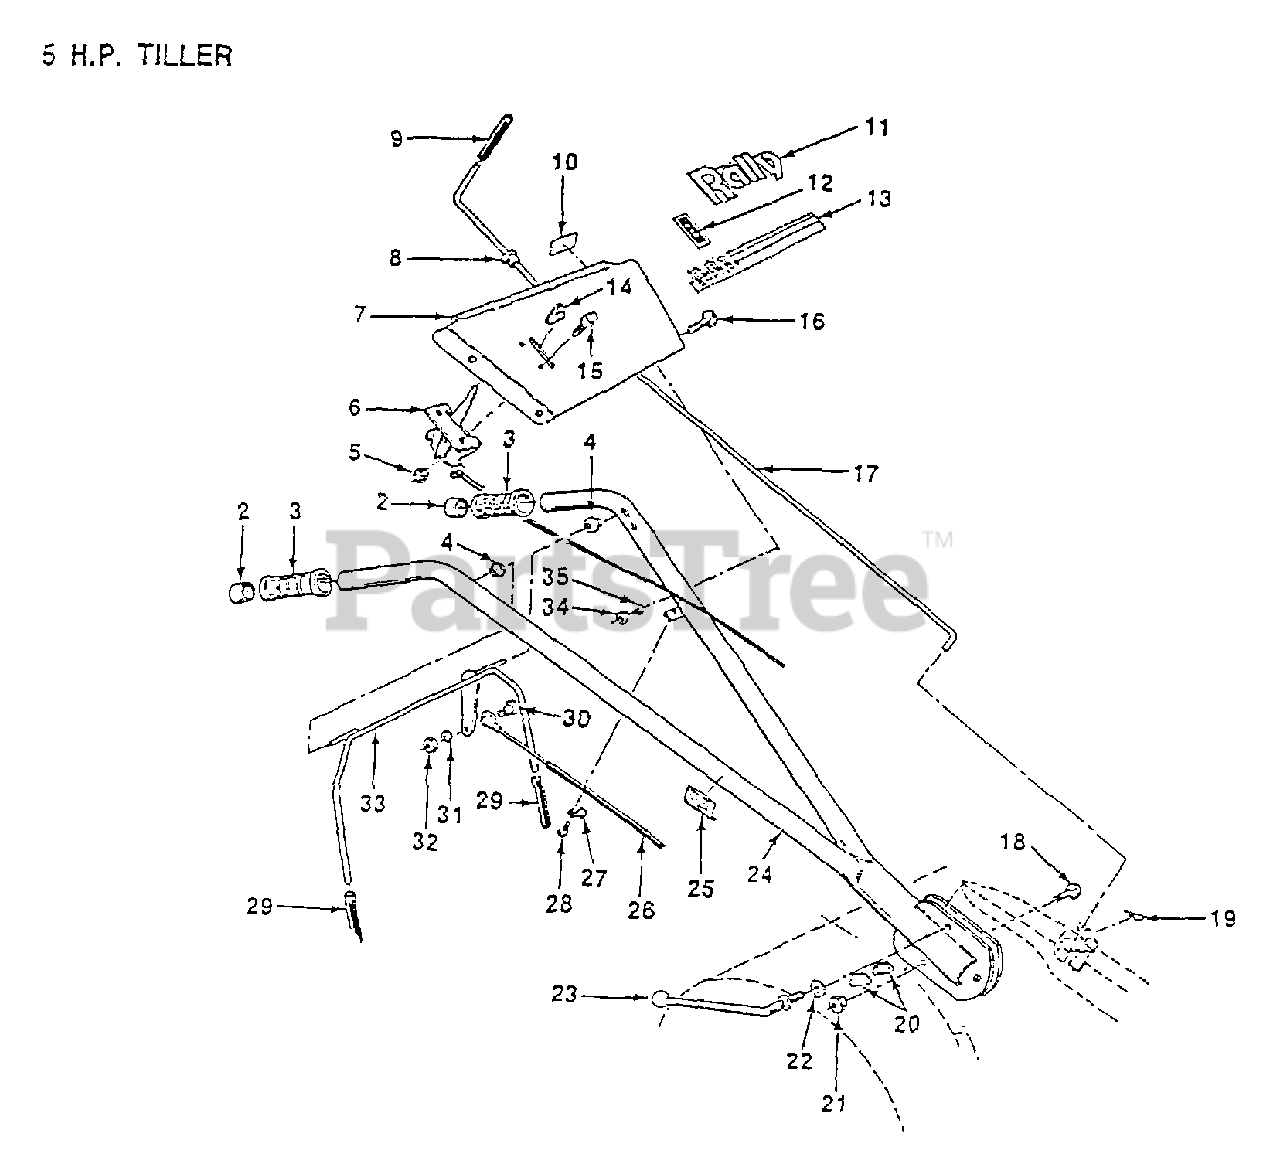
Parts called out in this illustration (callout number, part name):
2	CAP CRT
6	THROTTLE CRT
8	GROMMET TI
9	GRIP TI
12	DECAL, THROTTLE
13	DECAL, BRACKET HANDLE
14	KNOB CRT
15	SCREW
16	BOLT CARRIAGE CRT
17	ROD SHIFT CRT
18	BOLT D
19	RETAINER M
20	LOCK CRT
22	WASHER CRT
23	LEVER LOCK CRT
25	DECAL TI
26	CABLE.CLUTCH.CRT
27	CONDIUT CLIP T
29	GRIP BAR CRT
30	SHOULDER BOLT ST
31	LOCKWASHER
33	HANDLE BAR CRT
35	LOCKWASHER
